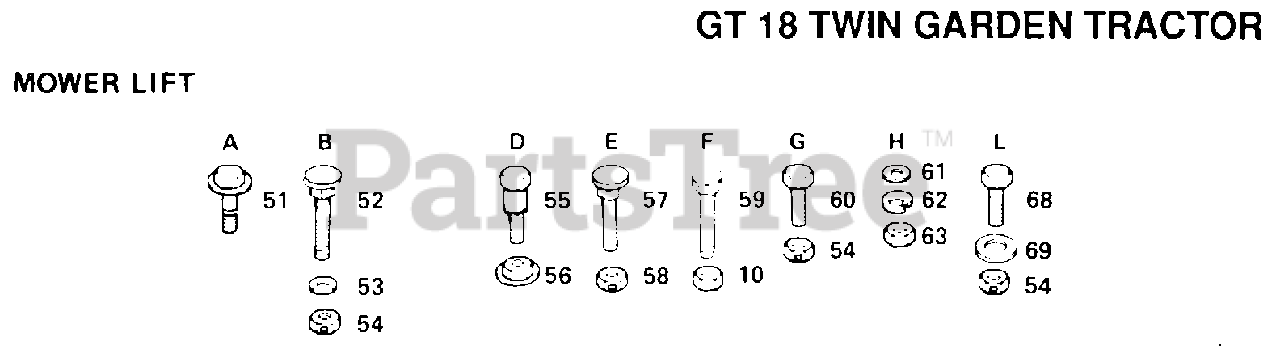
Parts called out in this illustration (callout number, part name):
51	SCREW LT
52	BOLT
53	WASHER
55	SHOULDER BOLT T
56	NUT T
57	BOLT
58	LOCKNUT
59	BOLT
60	BOLT
61	WASHER PM
68	BOLT
69	WASHER M
